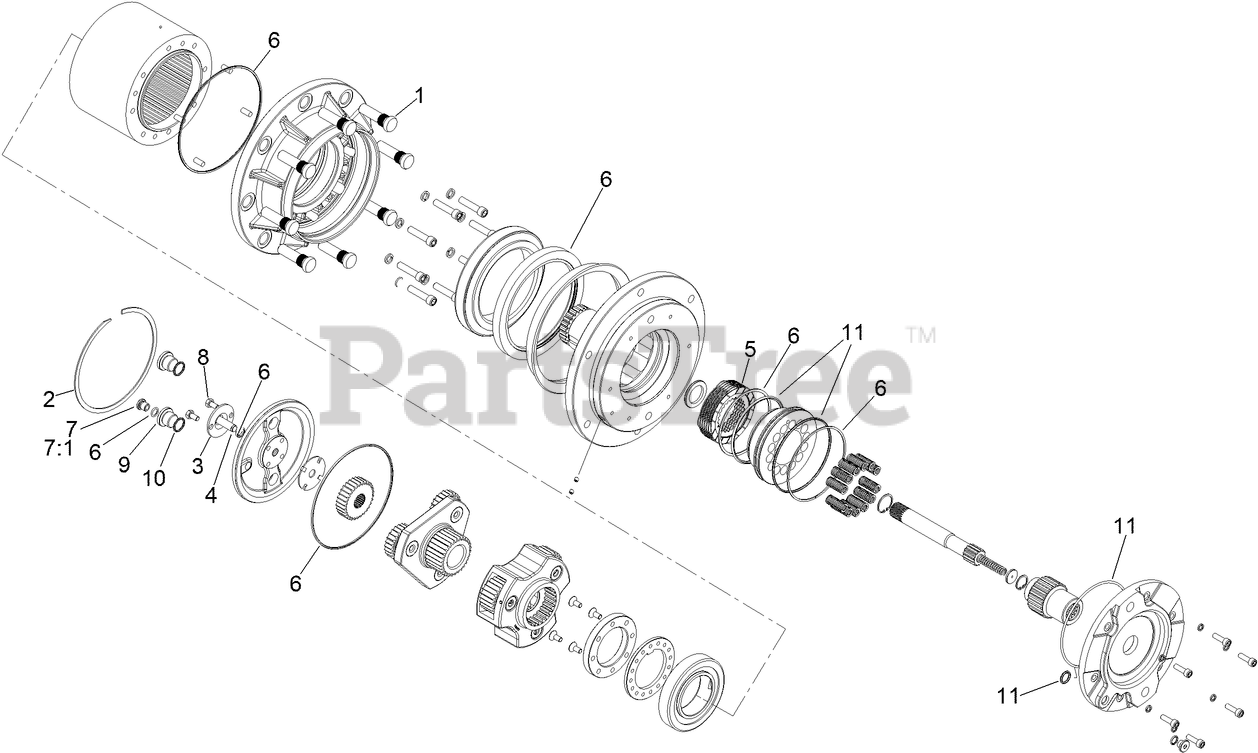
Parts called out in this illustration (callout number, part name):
1	STUD-WHEEL
2	RING-SNAP
3	CAP-LOCKOUT
4	PLUNGER
6	SEAL KIT-GEARBOX
7	PLUG ASM
7:1	O-RING
8	SCREW-HH
9	PLUG-FLANGE, MAGNETIC
10	O-RING M18
11	SEAL KIT-GEARBOX, BRAKE
